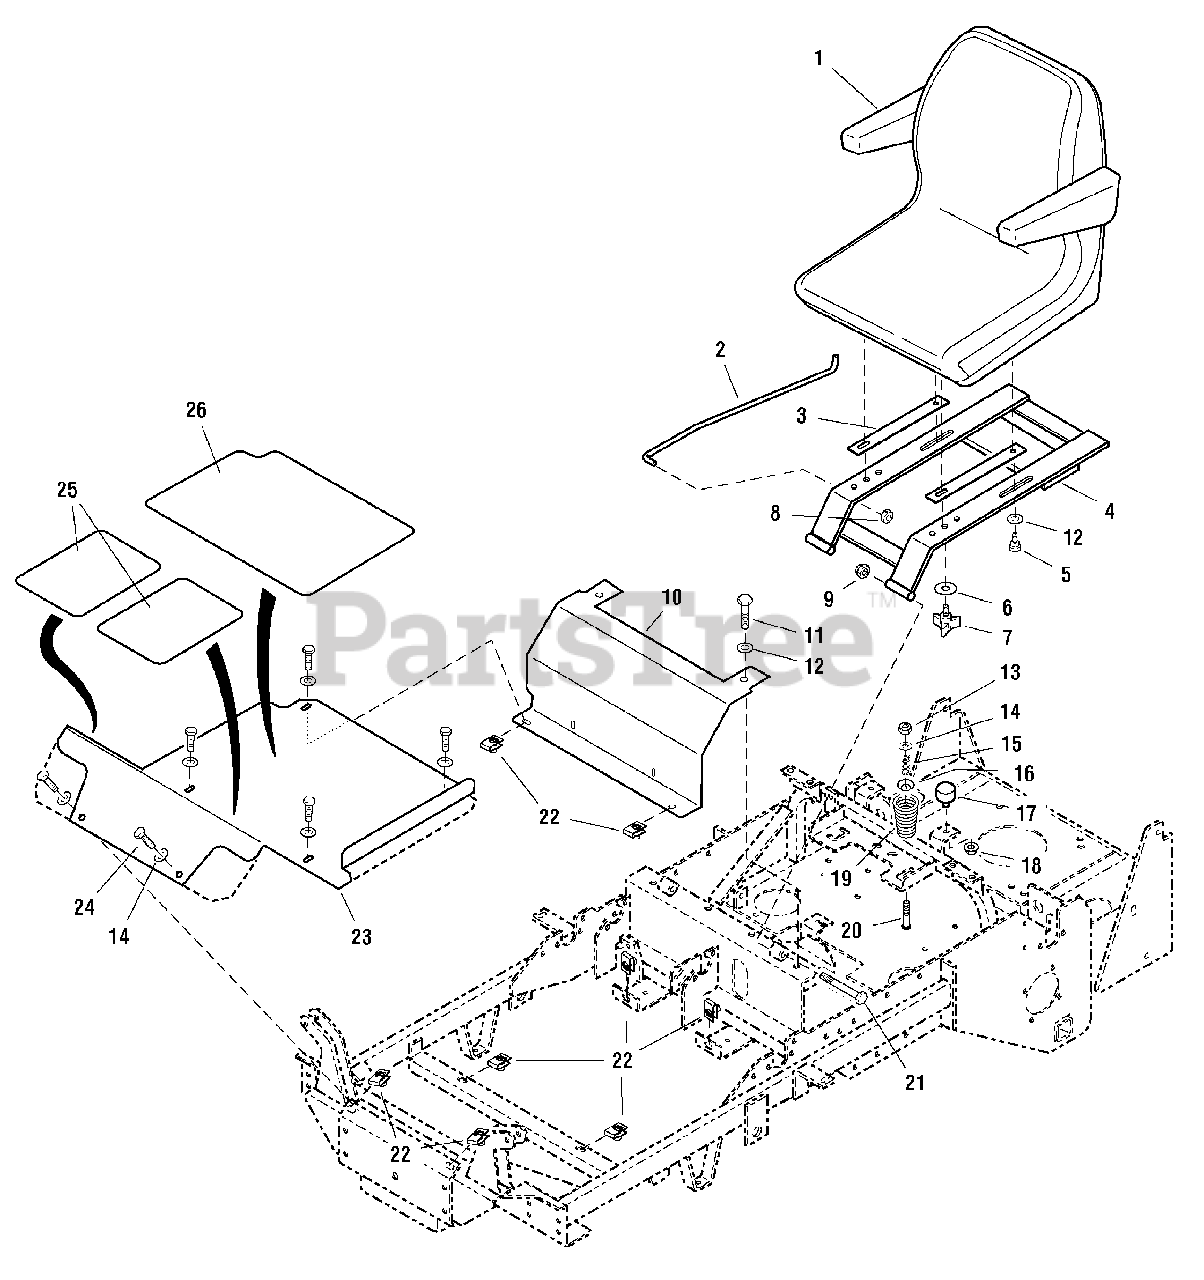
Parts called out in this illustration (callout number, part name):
2	ROD, Seat Stop
3	PLATE, Seat Slider, Orange
3	PLATE, Seat Slider, Red
4	SEAT MOUNT, Orange
4	SEAT MOUNT, Red
5	SHOULDER BOLT, 3/8 X 3/8
6	WASHER, Lock, INT-EXT, 5/16
8	COLLAR, Set, 5/16
9	NUT, Hex Nylon Lock, 3/8-16
10	PLATE, Brake Cover, Orange
10	PLATE, Brake Cover, Red
11	CAPSCREW, Hex Head, 3/8-16 X 2
12	WASHER, SAE, 3/8
13	NUT, Hex Nylon Lock, 5/16-18
14	WASHER, SAE, 5/16
15	SPRING, Compression
16	WASHER, Spring, 5/16 X 1-1/4
18	NUT, Hex Serrated Flange, 1/4-20
19	SPRING, Compression
20	CARRIAGE BOLT, 5/16-18 X 2
21	CAPSCREW, Hex Head, 3/8-16 X 4
22	BODY CLIP, 5/16-18
23	PLATE, Floor, Orange
23	PLATE, Floor, Red
24	CAPSCREW, Hex Head, 5/16-18 X 3/4
25	SAFETY WALK
26	SAFETY WALK, Orange Model Only
26	SAFETY WALK, 11.50 X 19.00, Red Model Only
